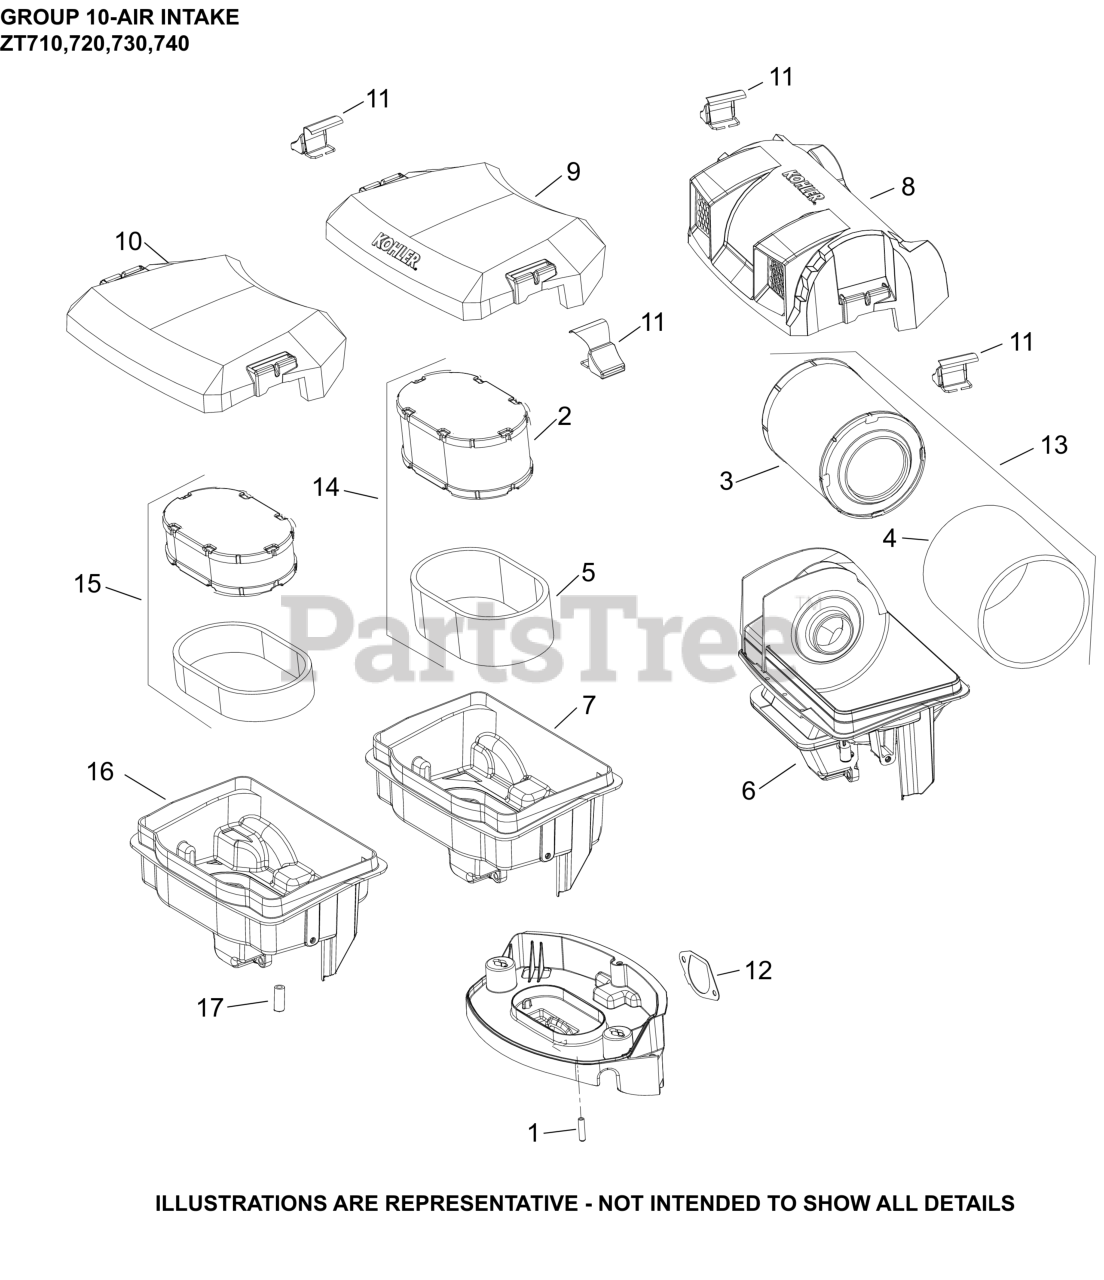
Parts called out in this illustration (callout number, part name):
1	CAP, MASKING
2	ELEMENT, AIR FILTER
5	ELEMENT, PRE-CLEANER
7	BASE, AIR CLEANER ASSEMBLY (LPAC)
9	COVER, AIR CLEANER (LPAC)
11	LATCH ASSY, AIR CLEANER COVER
12	GASKET, AIR CLEANER BASE
